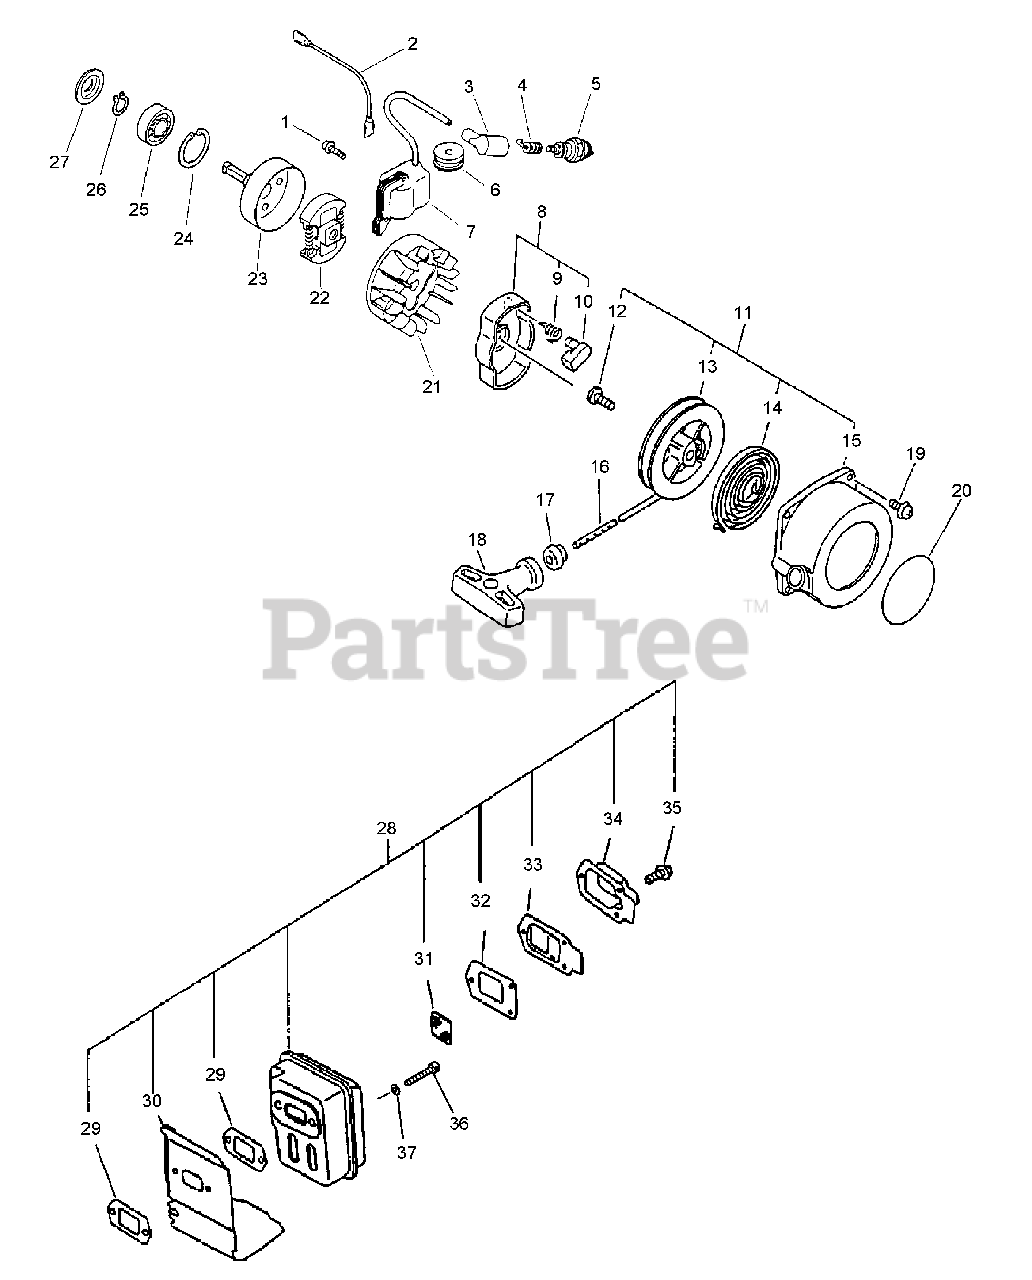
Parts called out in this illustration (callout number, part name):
1	SCREW - 4X22
2	LEAD - IGNITION
3	CAP, SPARK PLUG
4	TERMINAL, SPARK PLUG CAP
5	SPARK PLUG -- BPM-7A
5	SPARK PLUG -- BPMR-7A
6	GROMMET
7	COIL, IGNITION
8	STARTER PAWL ASSY
9	SPRING, RETURN
10	PAWL, STARTER - BLACK
11	STARTER ASSY
13	REEL, ROPE
14	SPRING, REWIND
15	CASE, STARTER
16	ROPE, STARTER - 3X1000
17	GUIDE, ROPE
18	GRIP, STARTER
19	SCREW - 4X16
20	LABEL - ECHO
21	FLYWHEEL
22	CLUTCH ASSY
23	DRUM, CLUTCH
24	RING, RETAINING - 32
25	BEARING, BALL - 6201
26	RING, RETAINING - 12
27	RETAINER, PIPE
28	MUFFLER ASSY
29	GASKET, EXHAUST
30	COVER, EXHAUST
31	SCREEN, SPARK ARRESTOR
32	GASKET, EXHAUST
33	GASKET, EXHAUST - INNER
34	GUIDE, EXHAUST - OUTER
35	SCREW - 4X10
36	SCREW - 5X55
37	WASHER - 5
